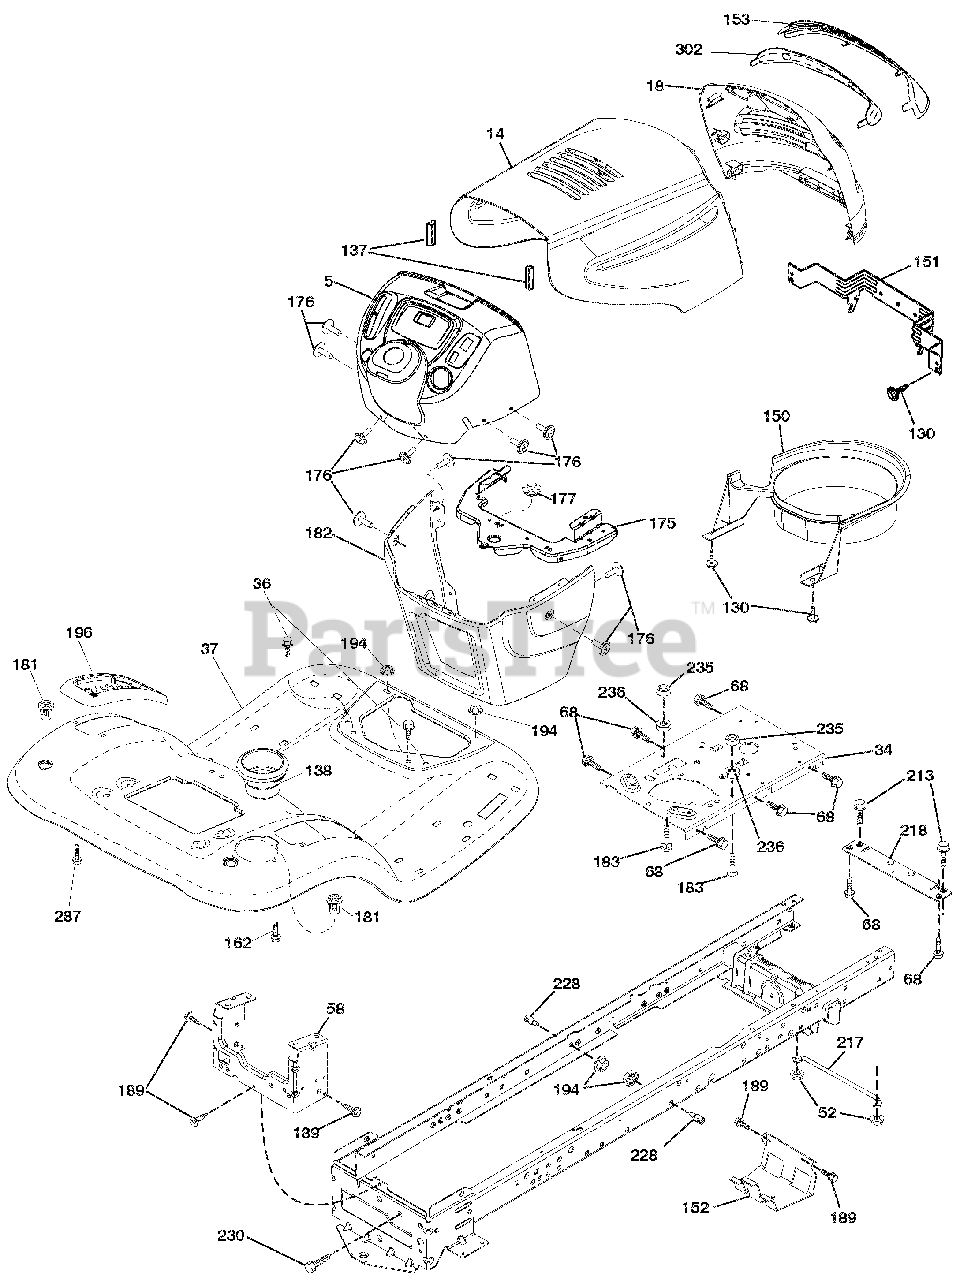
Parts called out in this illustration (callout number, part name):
5	DASH.P/L TEX.CBL CL.N/CHK.428
14	HOOD.PNT.ELITE.SPL-TP.N-SKIRTS
18	GRILLE ASM.ELITE BASIC.ARIENS
34	PLATE.ENGINE.WELDED.CHASSIS
36	SCREW.5/16-18X3/4.SMGML.TAP/R
37	FENDER.TLT.FS.W/CUPHLD.422
52	Nut, Hex, Crownlock 5/16-18
58	DRAWBAR.UPPER.2PC.SML.FENDER
68	SCREW.THDROL.5/16-18 X 1/2TYTT
137	BUMPER.HOOD.LARGE. 1.75"
138	CUPHOLDER.TL.TEX.428
150	AIR DUCT.INTAKE.B&S/HONDA.
151	BRACKET.PIVOT.LASR/ELTE/HUSQLT
152	SHIELD.BROWNING.W/TEX
153	LENS.BASIC.ARIENS
159	SCREW.HEXWSH THDR3/8-16X3/4.BL
162	SCREW.HEX.WSH.HI-LO.1/4X1/2UNC
175	CROSSMEMBER.LT
176	SCREW.#10-24X5/8.RND.QUDRX.GIM
177	BUSHING.STEERING.LT
180	CHASS.WLDMT.TL.12GA/2PC.18/22"
181	BUSHING.MNT.FEND.CRGO.BLK.TEX
182	DASH LOWER.LT.CCS
183	BOLT.FIN.HEX.5/16-18UNC X1-1/4
189	SCREW.5/16-18X3/4.SMGML.TAP/BL
194	Nut, Lock Hex Flange 5/16-18 u
196	CONSOLE ASM.DECKLFT.BL/RBT.TLT
213	Bolt, Hex Head 5/16-18 x 3/4
217	ROD.PIVOT.HOOD
218	X-PIECE.HOOD.STOP.NON/STEALTH
228	STUD.FASTNER.W/'D'ANTI-ROTATIO
230	BOLT SHOULDER 5/16-18
235	SPACER.FENDER
236	NUT.CENTER LOCK.5/16-18 UNC
287	SCREW.HEX.WASHEAD.1/4-20 X 3/8
302	INSERT.LENS.REFL.BASIC.LT
